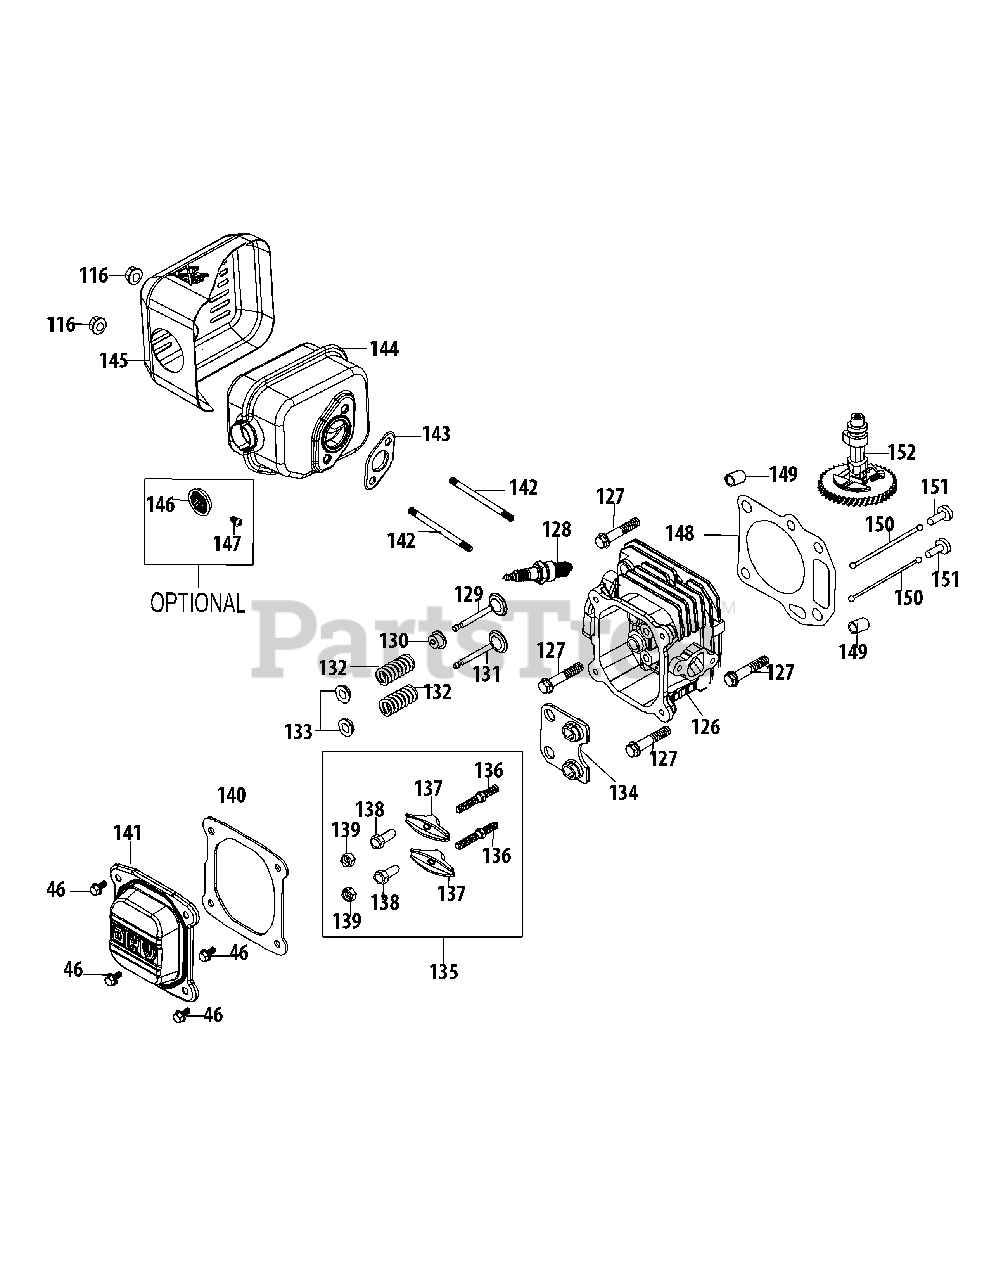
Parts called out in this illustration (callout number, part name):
46	Bolt M6X14 Multi-Purpose
116	Nut M6X10Mm Starter/Carb/Muff
126	Cylinder Head
127	Bolt M8X54 Cylinder Head
128	Spark Plug/F5Rtc
129	Intake Valve
130	Intake Valve Seal
131	Exhaust Valve
132	Valve Spring
133	Valve Spring Retainer
134	Push Rod Guide
135	Rocker Arm Assembly
136	Rocker Arm Stud
137	Rocker Arm
138	Fulcrum Nut
139	Jam Nut
140	Valve Cover Gasket
141	Valve Cover
142	Muffler Stud M6X95
143	Muffler Gasket
144	Muffler Assembly
145	Muffler Shield
146	Spark Arrestor
147	Spark Arrestor Screw
148	Cylinder Head Gasket
149	Cylinder Head Dowel Pin 10×16
150	Push Rod
151	Tappet
152	Camshaft Assembly
